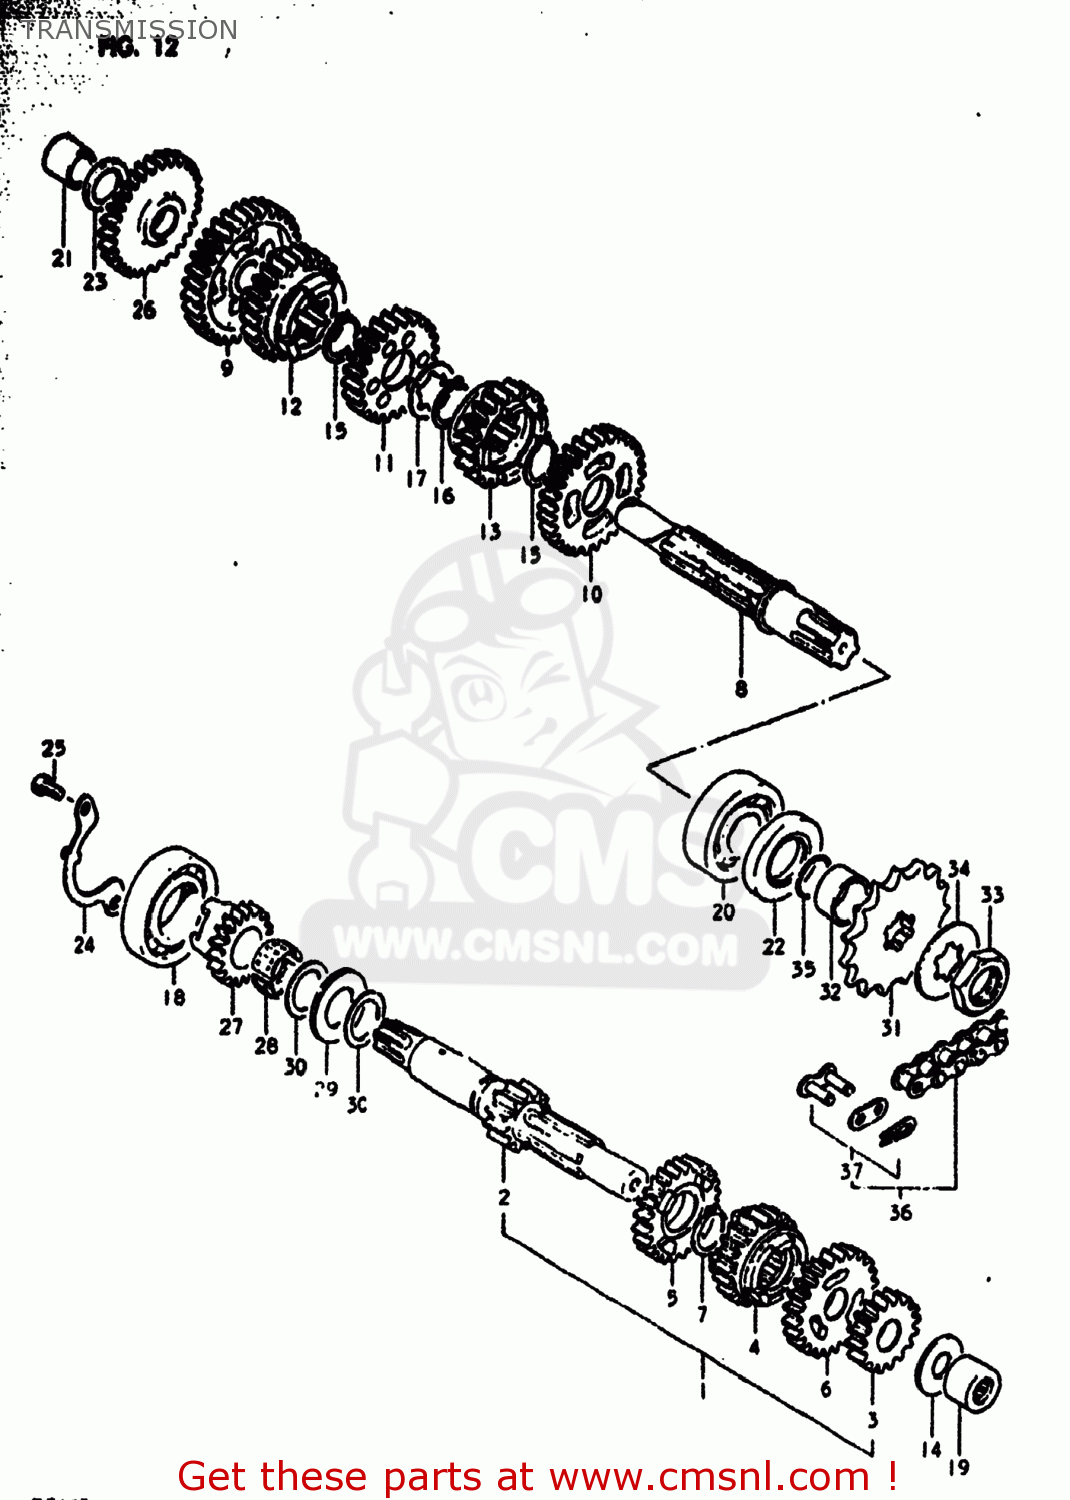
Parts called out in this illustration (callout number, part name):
1	SHAFT,COUNTER
2	SHAFT,COUNTER
3	GEAR,2ND DRIVE
4	GEAR,3RD DRIVE
5	GEAR,FOURTH DRIVE
6	GEAR,5TH DRIVE
7	CIRCLIP
8	SHAFT,DRIVE
9	GEAR,1ST DRIVEN
10	GEAR,2ND DRIVEN
11	GEAR,THIRD DRIVEN
12	GEAR,FOURTH DRIVEN
13	GEAR,FIFTH DRIVEN
14	WASHER
15	CIRCLIP
16	CIRCLIP
17	WASHER
18	BEARING, RH
19	BEARING(15X22X15)
20	BEARING
21	BUSH
22	OIL SEAL (25X44X7)
23	WASHER
24	RETAINER,CNTR SHAFT BEARING
25	SCREW 6X12
26	GEAR,KICK STARTER IDLE
27	GEAR,KICK STARTER DRIVEN
28	BEARING(19.2X23.2X19)
29	BEARING(21X32X2.85)
30	WASHER(21X30X0.8)
31	SPROCKET,ENGINE
32	SPACER(20X25X12.5)
33	NUT
34	WASHER,LOCK
35	O RING(D:1,ID:19.5)
36	CHAIN ASSEMBLY,DRIVE
37	JOINT
